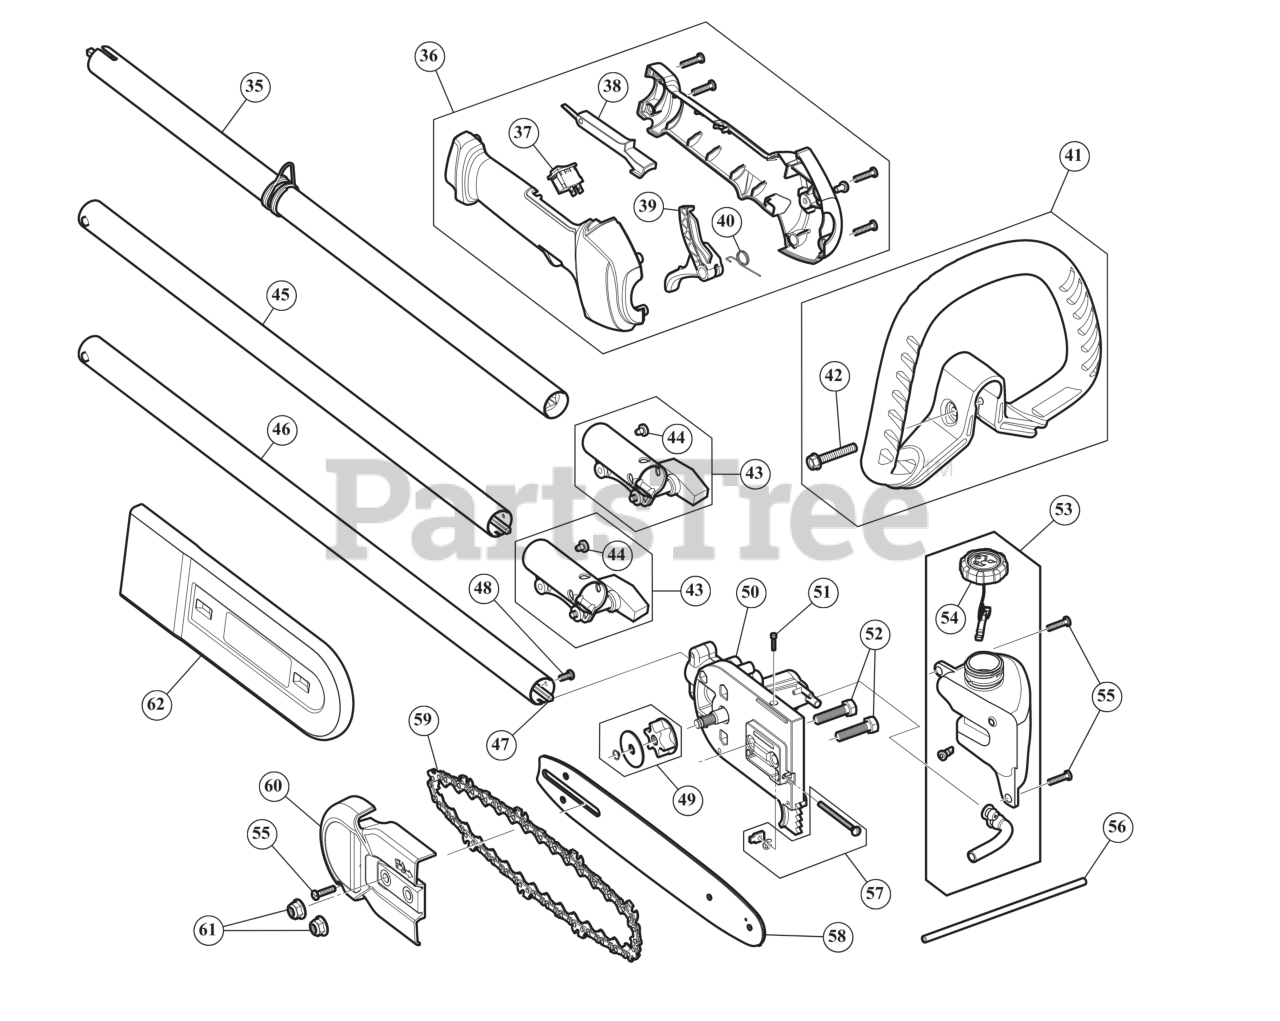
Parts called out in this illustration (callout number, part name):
35	BOOM ASSEMBLY UPR
36	THROTTLE GRIP ASSEMBLY
37	SW, MOMENTARY ON/O
38	LEVER LOCK OUT
39	THROTTLE TRIGGER
40	TRIGGER SPRING
41	HANDLE ASSEMBLY
42	BOLT 1/4-20X1 1/2
43	SPLIT BOOM COUPLER KIT
44	SCREW, 10-32X.250 TA
45	EXTENSION BOOM ASSEMBLY
46	LOWER DRIVE SHAFT HOUSING
47	FLEXIBLE DRIVE SHAFT
48	SCREW 1/4-20 X.500
49	SPROCKET ASSEMBLY
50	GEAR BOX ASSEMBLY
51	SCREW 4X40X.50
52	SCREW 5/16-18 x 1.25 GR5
53	OIL TANK
55	SCREW, #8-16X.750 PH
57	CHAIN TENSION HDW
60	CHAIN GUARD
61	FLANGE LOCK NUT 5/16-18
